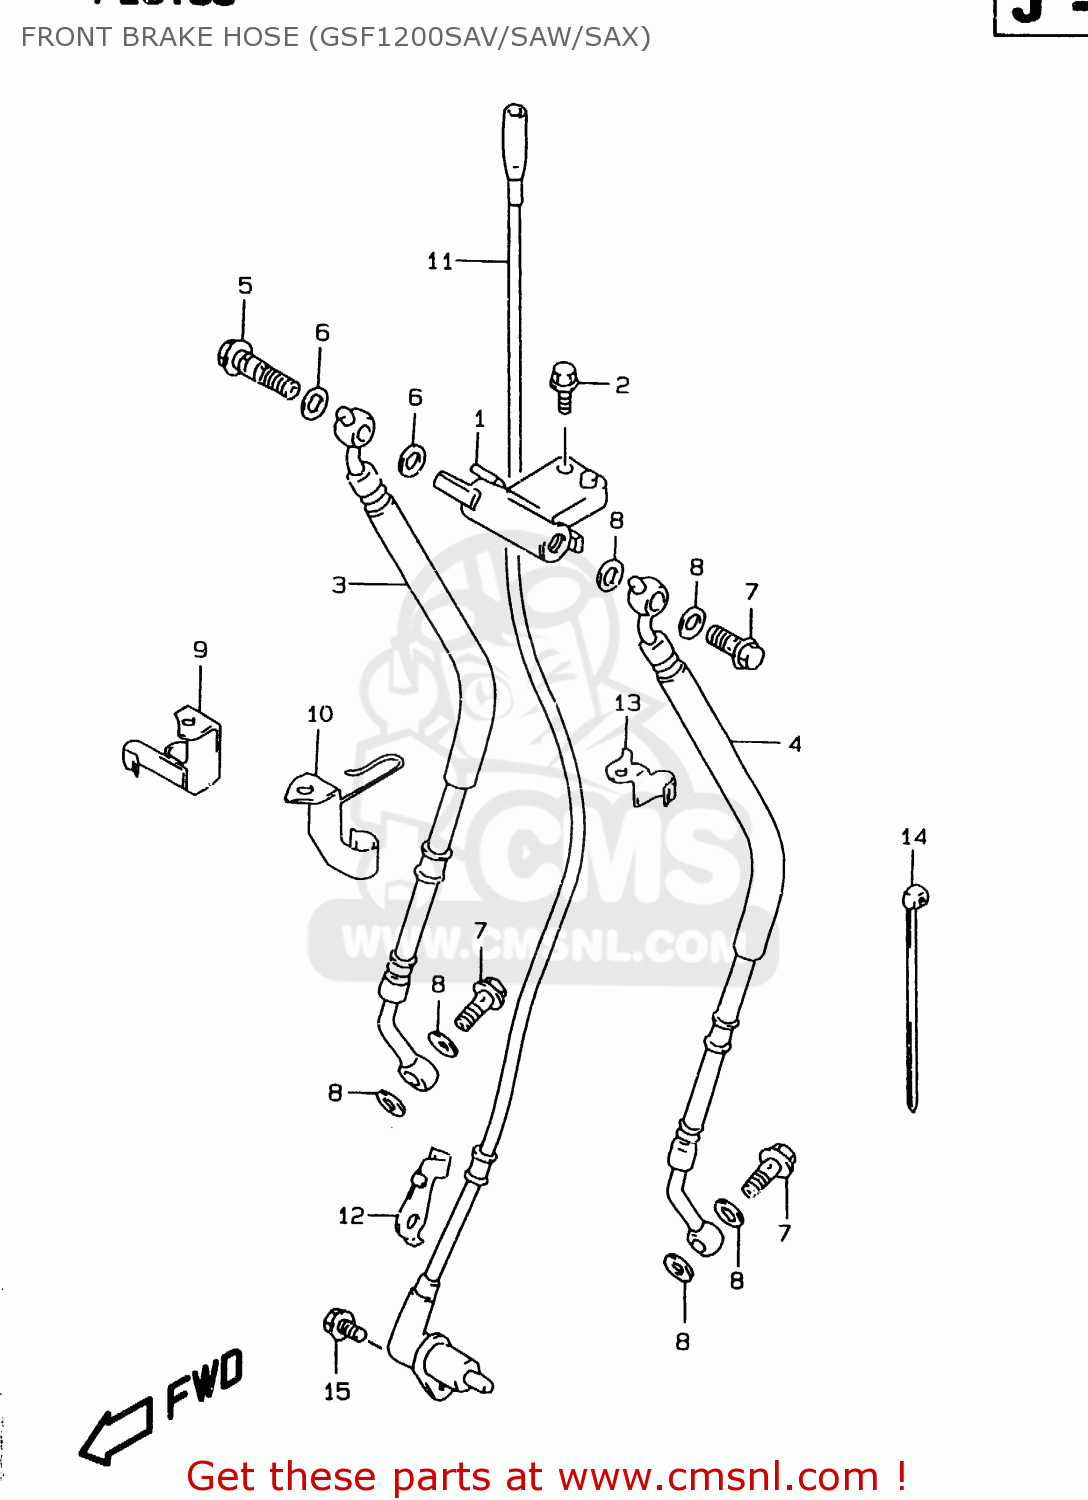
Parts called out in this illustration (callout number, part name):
1	JOINT,BRAKE HOSE
2	BOLT
3	HOSE,FR BRAKE NO.2,R
4	HOSE,FR BRAKE NO.2,L
5	BOLT UNION
6	WASHER(10X15X1.5)
7	BOLT UNION
8	WASHER(10X15X1.5)
9	CLAMP,FR BRAKE HOSE,R
10	CLAMP,FR BRAKE HOSE,L
11	SENSOR,FR WHEEL ABS
12	CLAMP,ABS SENSOR FORK
13	CLAMP,ABS SENSOR FR JOINT
14	CLAMP(L:145)
15	BOLT
